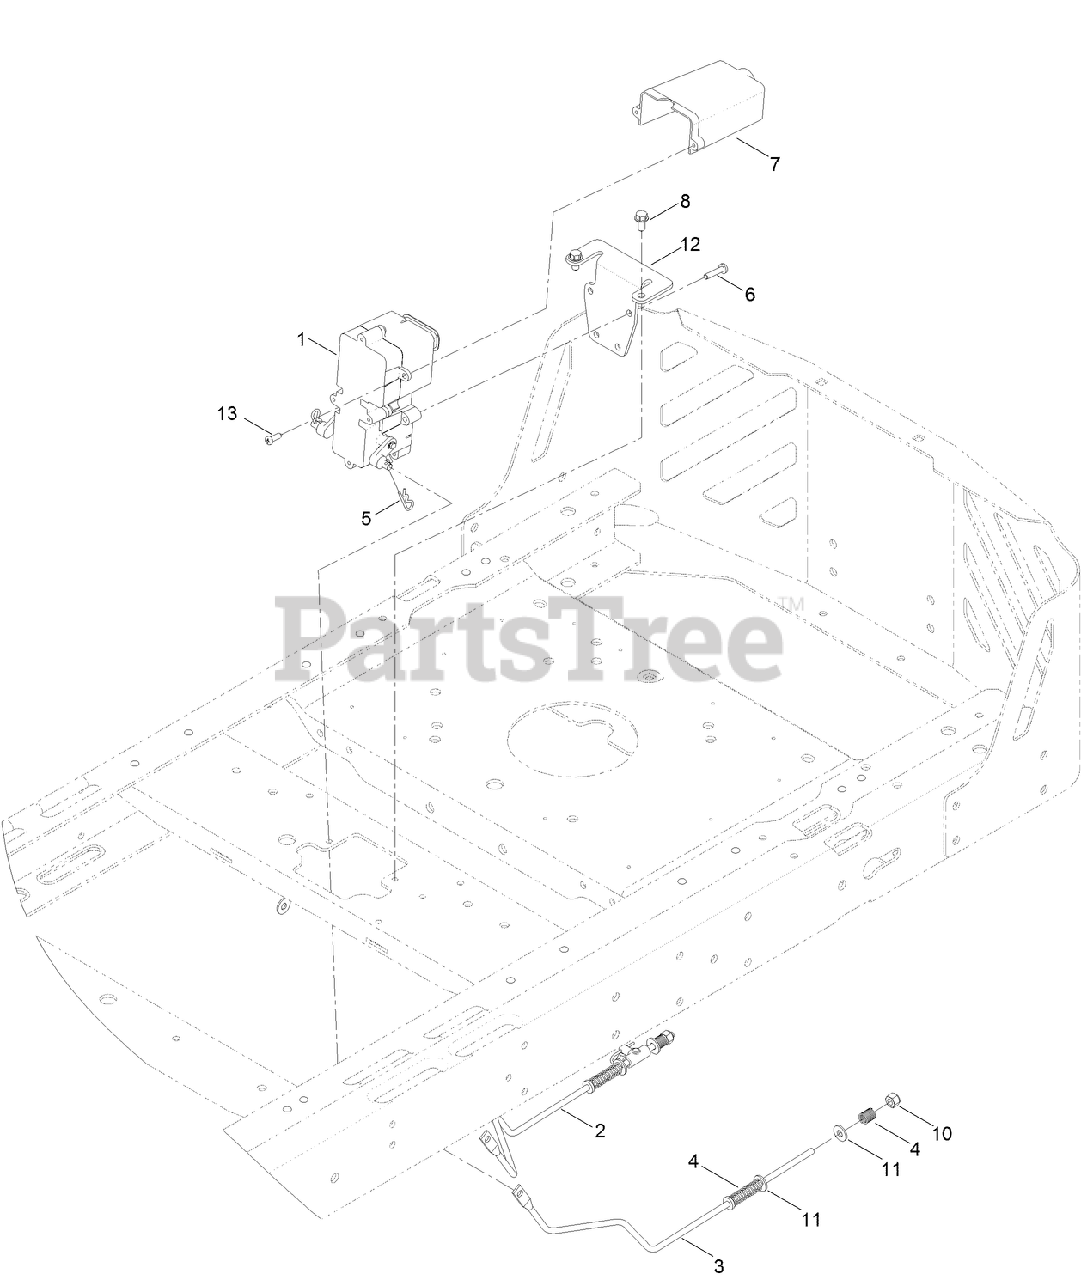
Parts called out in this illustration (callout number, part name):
2	ROD-BRAKE, RH
3	ROD-BRAKE, LH
4	SPRING-COMPRESSION
6	SCREW-PPH
8	SCREW-HWH
10	NUT-LOCK, NI
11	WASHER
12	BRACKET-MOUNT, BRAKE
13	SCREW-PPH
